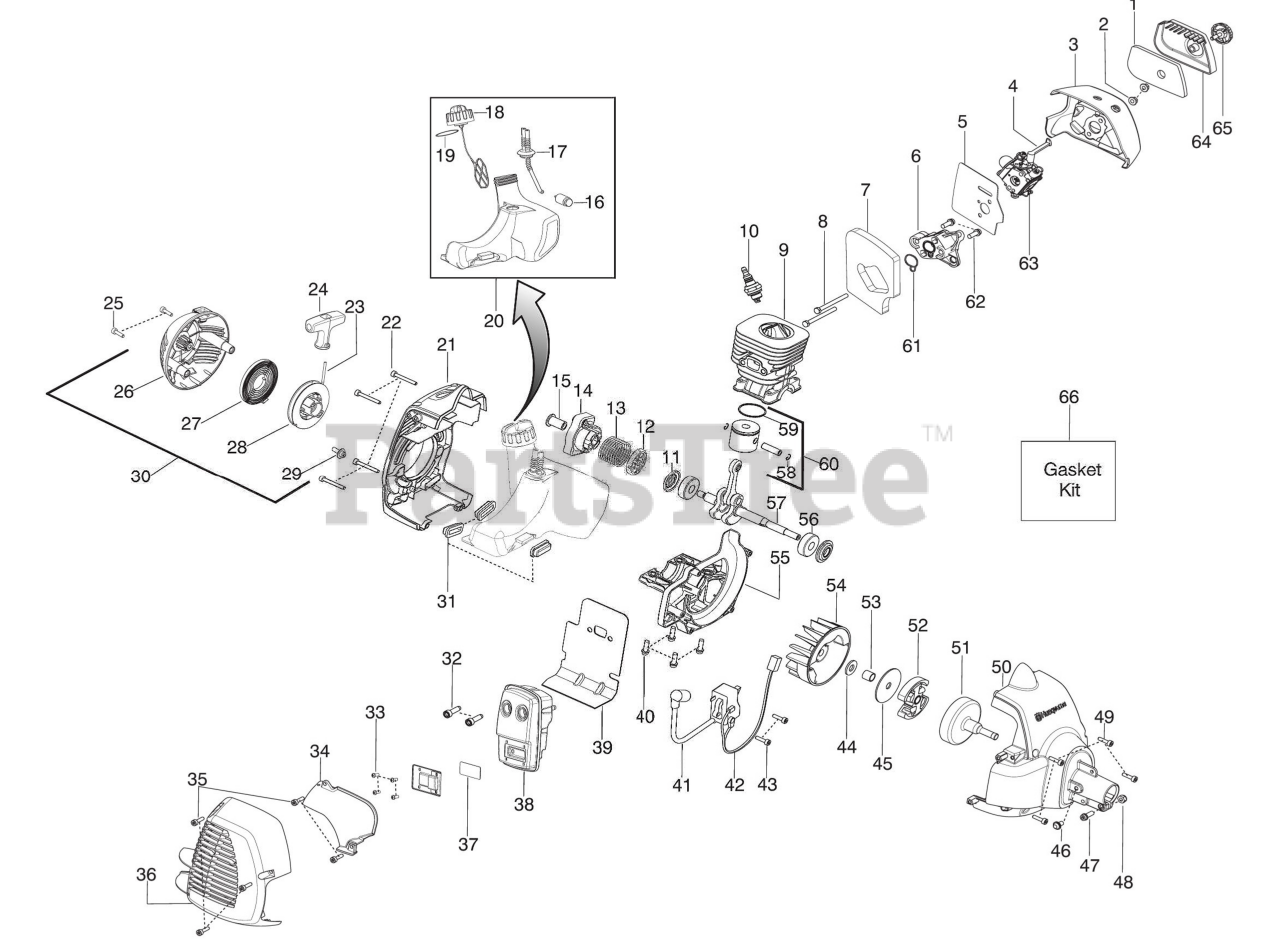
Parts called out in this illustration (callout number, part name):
2	Nut-Carb. Screw
3	Air Box
4	Lever - Choke
5	Kit-Carb. Gasket
6	Adaptor-Carb.
7	Kit-Gasket
9	Cylinder
10	Plug-Spark (RCJ-6Y)
11	Kit-Crankshaft seal
12	Washer-Starter
13	Spring-Starter Cup
14	Assy-Starter Cup
15	Coupling-Starter
16	Assy-Fuel Filter
17	Kit-Fuel Line
18	Assy-Cap w/ret.
19	Kit Gasket O-ring - Fuel Cap
20	Assy-Fuel Tank
21	Shroud-Rear
24	Handle-Starter
25	Screw
26	Starter Hsg. w/eyelet
27	Kit-Starter Spring
28	Kit-Starter Pulley
30	Assy-Starter Hsg.
31	Isolator-Tank
32	Bolt-Muffler
34	Shield-Heat
36	Guard-Muffler
37	Kit-Spark Arrestor
38	Assy-Muffler
39	Kit-Gasket-Paper met.
41	Module
42	Assy-Leadwire
45	Washer-Clutch
50	Assy-Fan Housing
51	Assy-Clutch Drum
52	Kit-Clutch Assy.
55	Crankcase
57	Kit-Crankshaft
58	Retainer-Piston Pin
59	Ring-Piston
60	Kit-Piston
61	Kit-Gasket
63	Kit-Carb.
64	Cover-Air Box
66	Kit-Gasket
